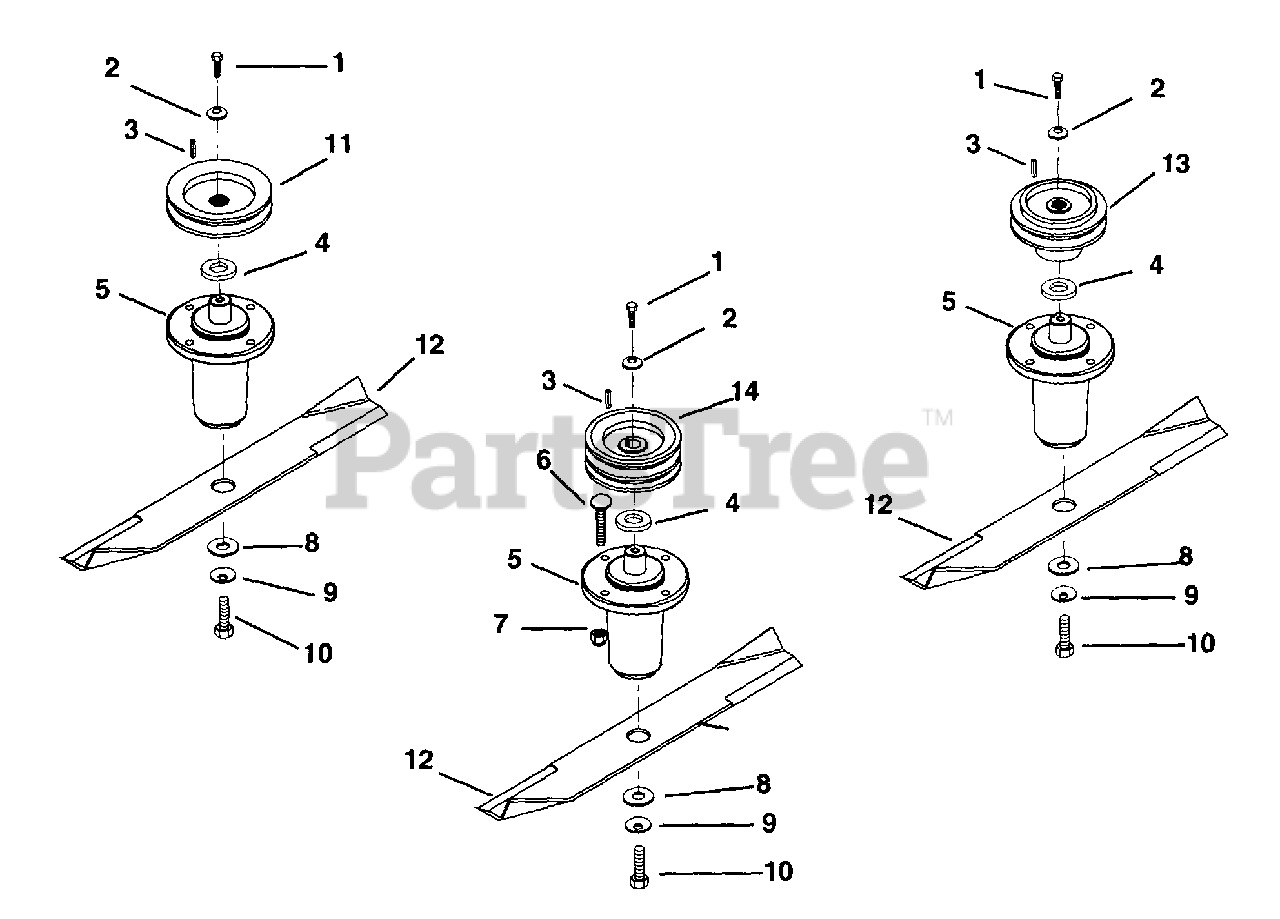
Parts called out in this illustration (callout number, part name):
1	Bolt-Hex .38-16 x 1.00 Grade 8
2	Washer-Cupped Serrated .375
3	Key-Square .25 x 1.00 x .25
4	Slinger-Dust
5	Maintenance Free Spindle Assembly
6	Bolt-Round Head Square Neck .38-16 x 1.50
7	Nut-Locking-Nylon .38-16
8	Washer-Flat Steel .640 x 1.81 x .250
9	Washer-Bellville .63 x 1.625 x .14
10	Bolt-Blade
11	Weldment, Pulley-V 60" Mower 5.50 x 1.004 with Key
11	Weldment, Pulley-V 50" Mower 3.50 x 1.004 with Key
12	Blade, 60" Mower Tungsten Carbide
12	Blade, 50" Mower Tungsten Carbide
13	Weldment, Pulley-V 60" Mower 5.40X1.004 with caps
13	Weldment, Pulley-V 50" Mower 4.75 x 1.004 with Caps
14	Pulley-60" Mower Double V 2 x 5.660 x 1.004 with Key
14	Pulley-50" Mower Double V 5.20 x 3.50 x 1.004 with Key
